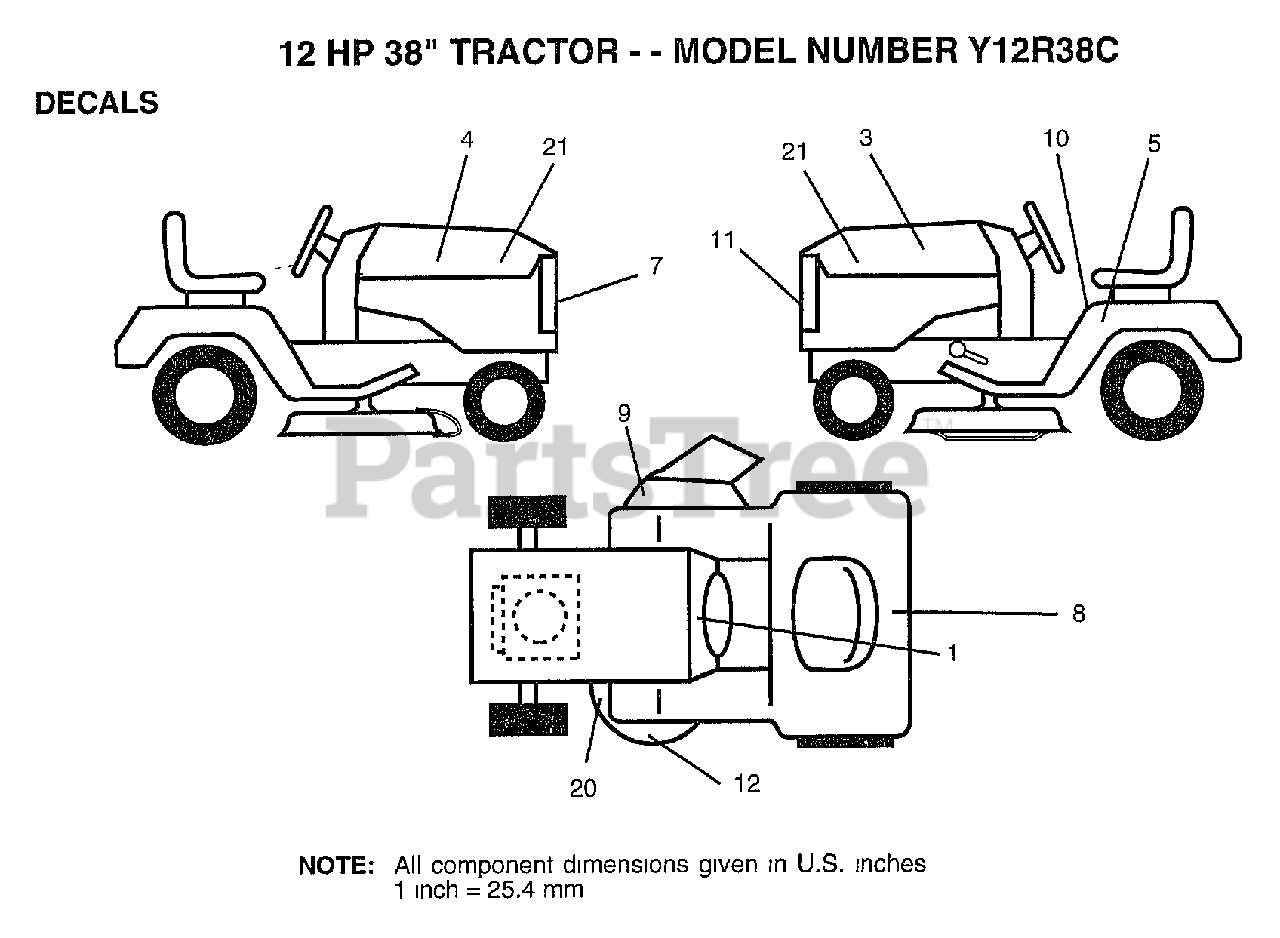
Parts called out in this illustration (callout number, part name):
1	DECAL.INST.OPER.
5	IND HGT DECK DECA
6	DECAL.ENG.272632
7	DECAL.GRILL.YARDP
9	"DECAL, WARNING"
10	DECAL CAUTION
11	"DECAL,LIGHT BOX"
20	DECAL
21	DECAL.PANEL.SD.12
